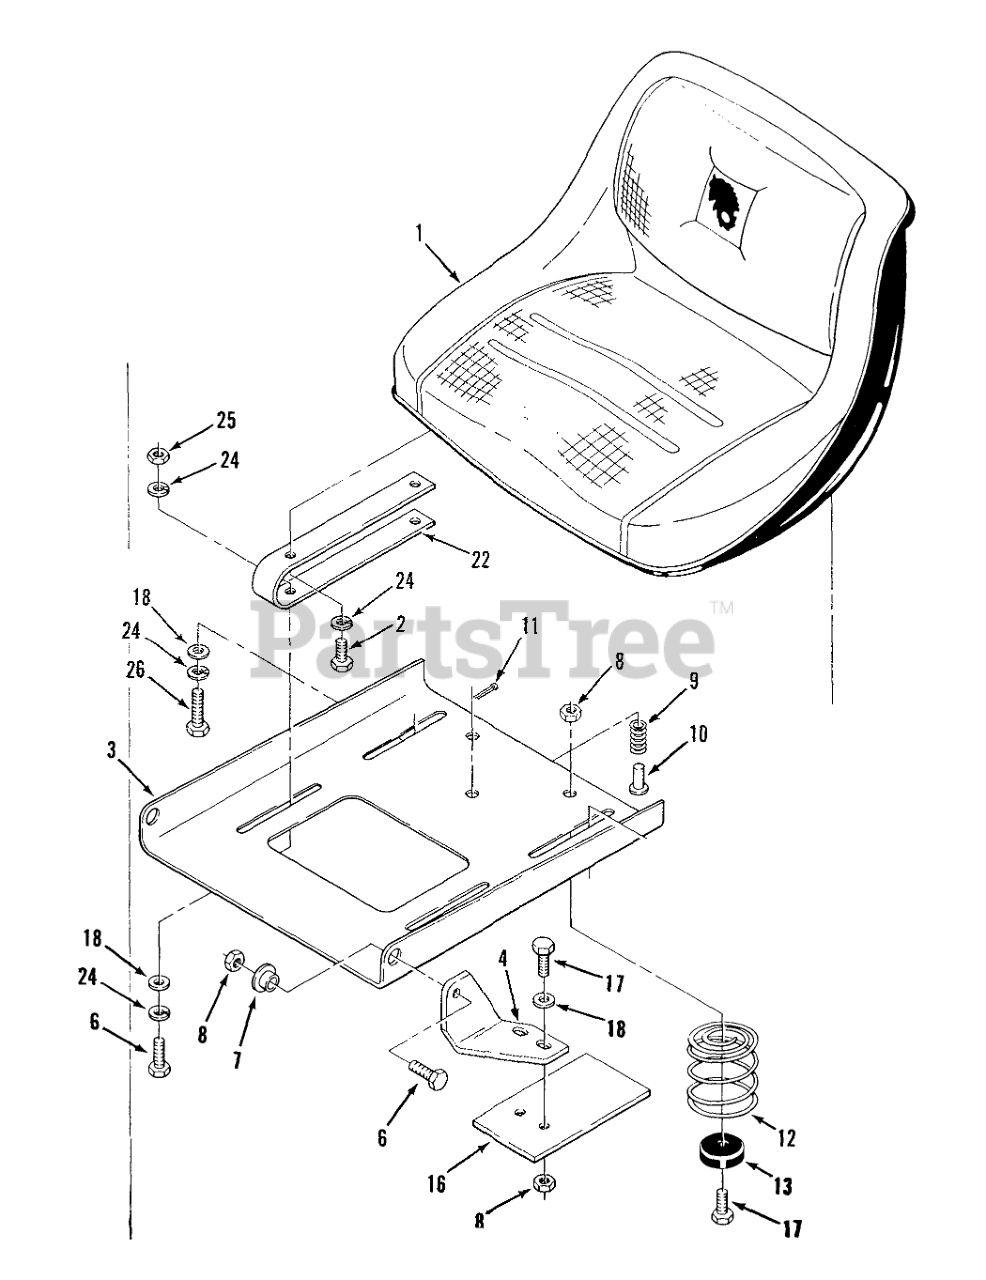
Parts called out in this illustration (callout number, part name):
1	Seat 312, 414
2	Bolt
3	PLATE-SEAT PIVOT B
4	Bracket-Pivot RH
6	HHCS
7	BUSHING
8	Nut
9	SPRING-SEAT SWITCH
11	Cotter Pin
12	Spring-620-Z
13	BUMPER
16	PLATE R
17	Bolt
18	WASHER 5/16 SAE
22	SPRING-SEAT B
24	Lockwasher
25	Nut
26	Bolt
